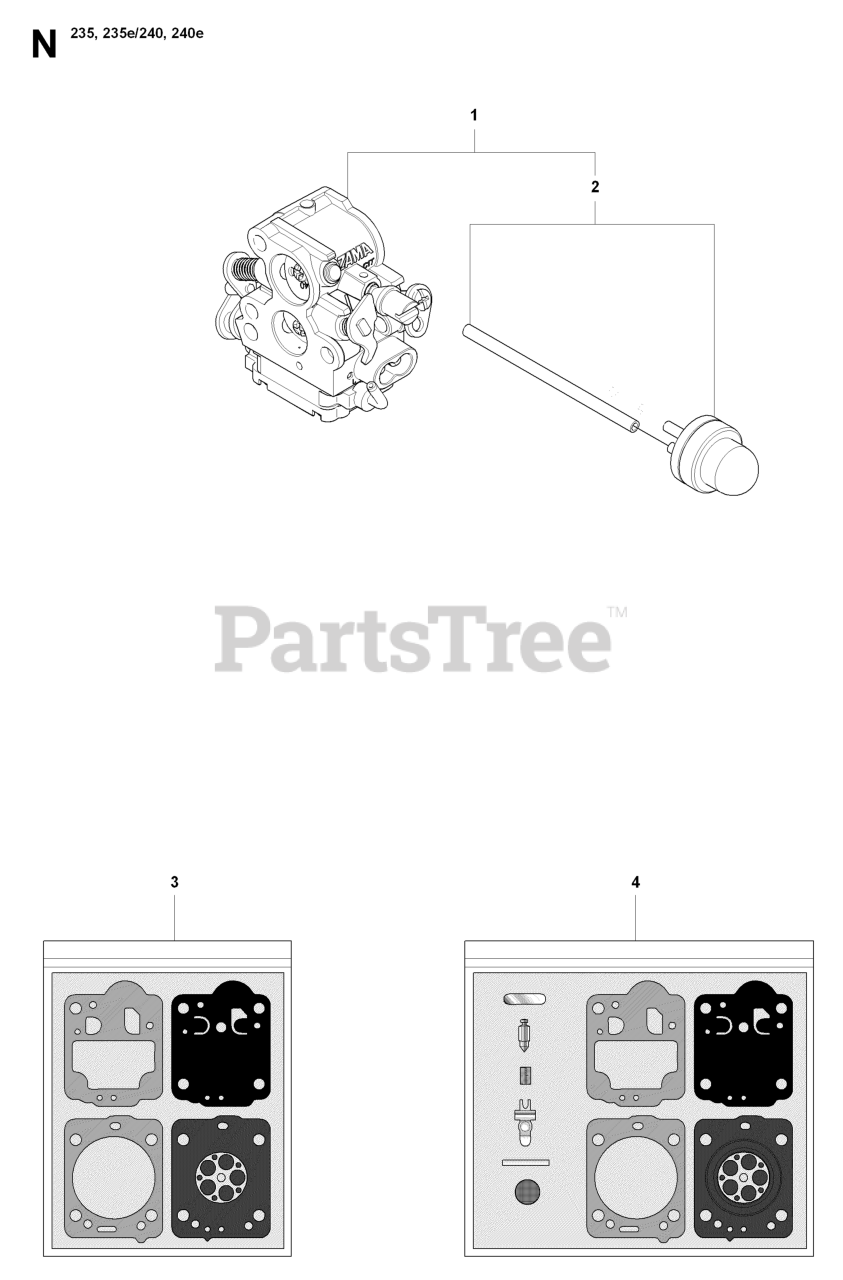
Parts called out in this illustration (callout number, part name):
1	%CARBURETOR
2	PURGE & LINE ASSY
3	KIT CARB GASKET
4	KIT CARB REPAIR
